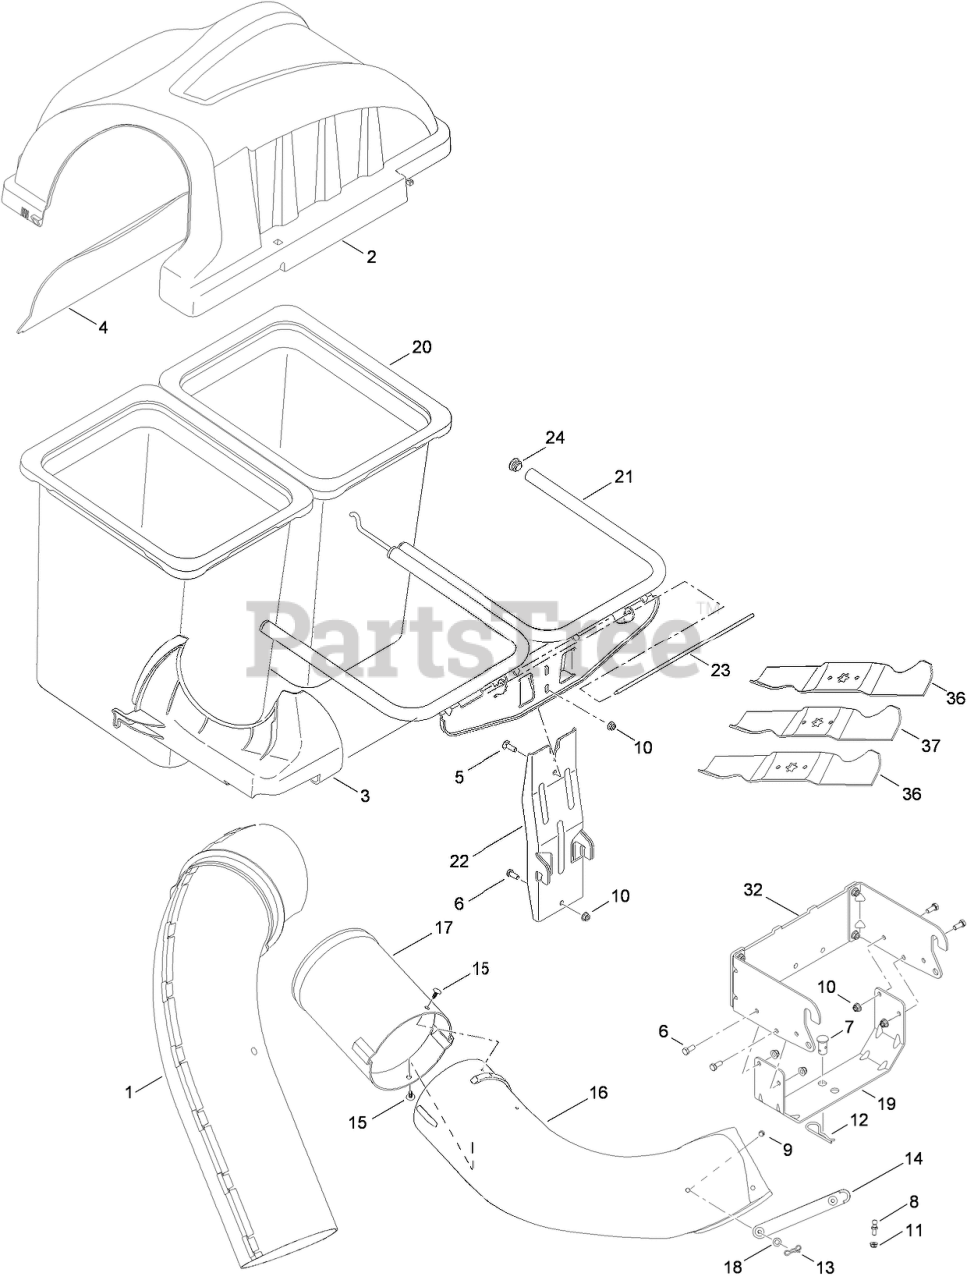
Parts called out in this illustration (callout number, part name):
1	UPPER CHUTE ASM
2	DOUBLE BAGGER COVER ASM
3	SUPPORT-CHUTE, UPPER
4	SCREEN-COVER, BAGGER
5	BOLT-CARR
6	SCREW-HH
7	PIN-CLEVIS
8	PIN-CATCHER, GRASS
9	PIN-CLEVIS
10	NUT-LOCK, FLANGE
11	NUT-LOCK, FLANGE
12	CLIP-HAIRPIN
13	PIN-COTTER
14	STRAP-CHUTE
15	CLIP-RATCHET, FASTENER
16	CHUTE-DISCHARGE
17	ADAPTER-CHUTE, BAGGER
18	WASHER-BELL
19	SUPPORT-BRACKET, UNIVERSAL
20	GRASS BAG ASM
21	DOUBLE BAG SUPPORT ASM
22	BRACKET-SUPPORT, VERTICAL
23	PIN-HINGE, COVER
24	PLUG-END
32	HITCH BRACKET ASM
36	BLADE (2 IN 1 STAR, 16.28 INCH)
37	BLADE (2 IN 1 STAR, 14.88 INCH)
